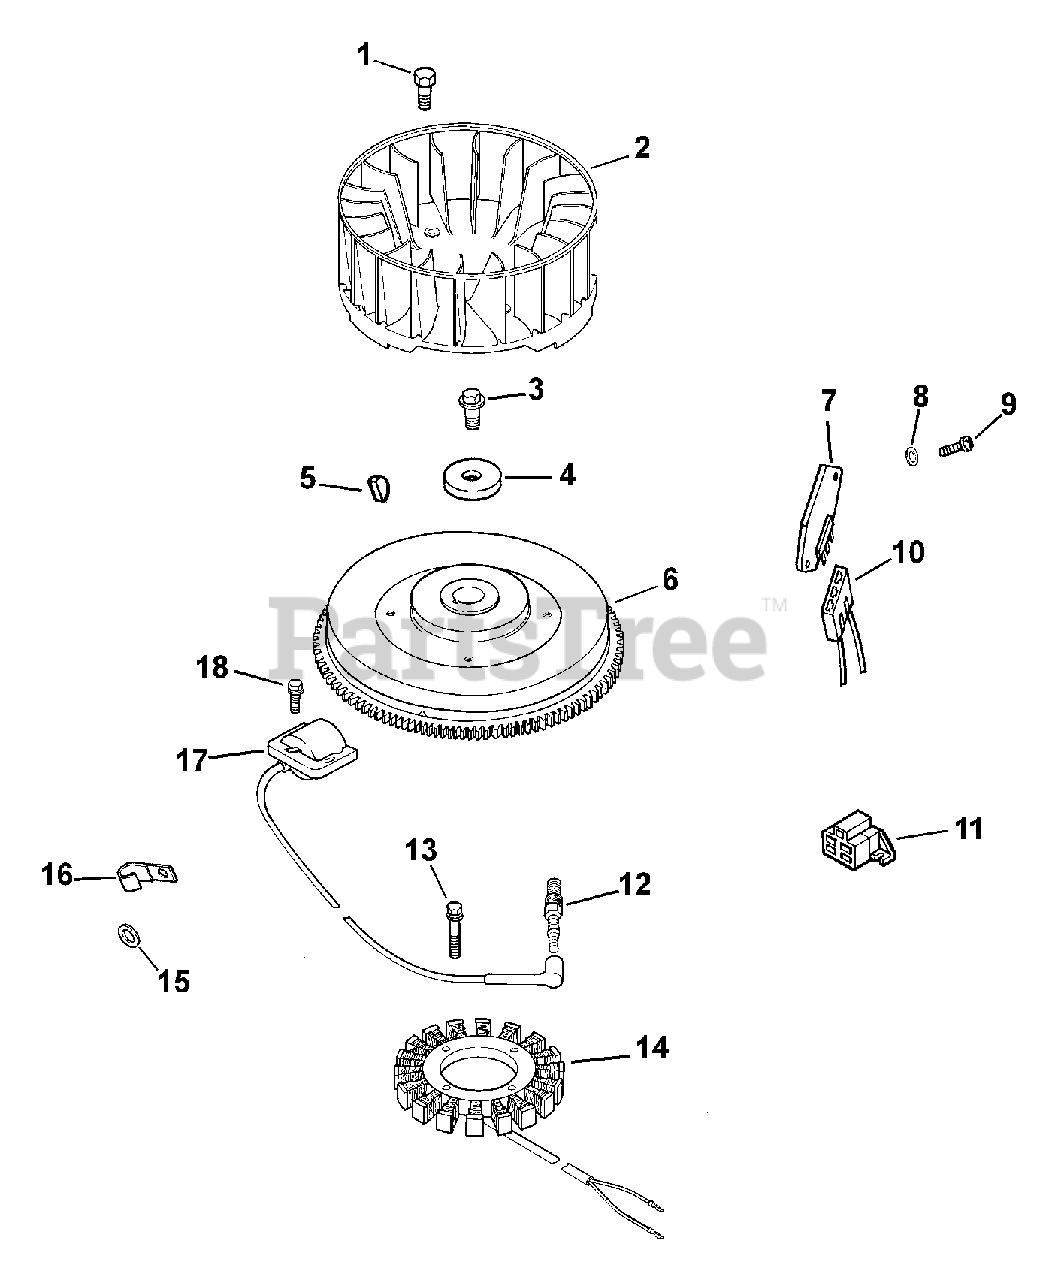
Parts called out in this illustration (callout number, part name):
1	BOLT, SHOULDER
2	FAN - DISCONTINUED
3	SCREW, FLG M10X1.5X45 - (#25086361S)
4	WASHER, FLAT 13/32"
5	KEY, 3/16" X 5/8"
6	FLYWHEEL (PAINTED)-USE 24 025 20-S
9	SCREW, HEX WASHER HEAD
10	CONNECTOR, BODY (KM)-USE 25 155 41-S
11	CONNECTOR
12	SPARK PLUG
13	SCREW, M5X0.8X25 - (#25086402S)
14	KIT, 15 / 20 AMP STATOR
15	WASHER, FLAT 1/4" (O.D. 1/2")
16	CLIP, CABLE
17	MODULE, IGNITION (#DSC)
18	SCREW, FLG THD FRM M5X.8X20-(#25086399S)
